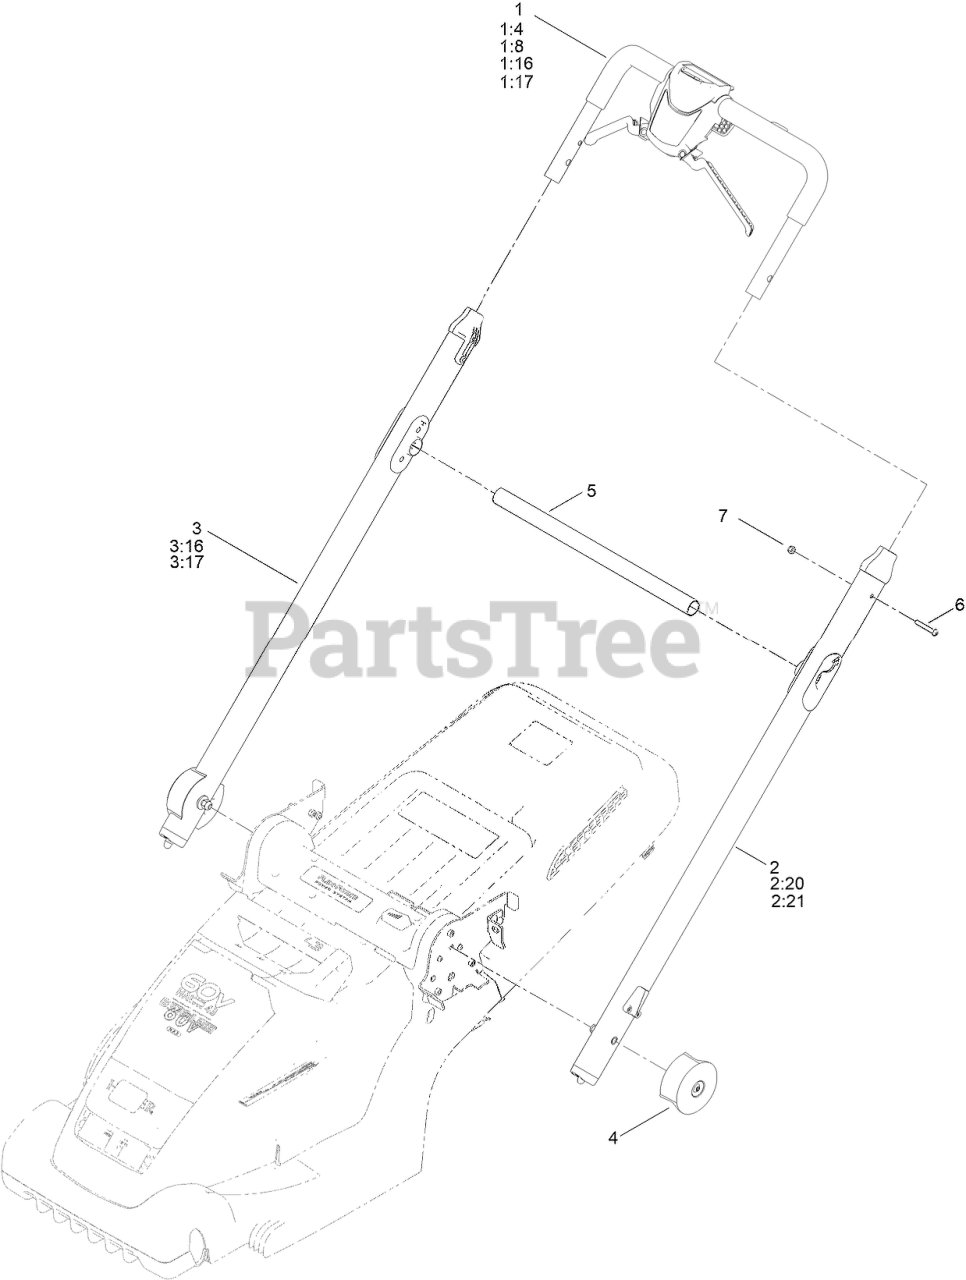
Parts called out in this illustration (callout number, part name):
1	CONTROL LEVER ASM, PROPELLED
1:4	TOP BUTTON KIT
1:8	UPPER LEVER KIT (43)
1:16	LOWER LEVER KIT
1:17	SPEED CONTROLLER WHEEL KIT
2	HANDLEBAR ASM, LH
2:20	HANDLEBAR BRACE - INNER
2:21	HANDLEBAR BRACE, OUTER
3	HANDLEBAR ASM, RH
3:16	HANDLEBAR BRACE - INNER
3:17	HANDLEBAR BRACE, OUTER
4	HANDLEBAR END CAP
5	BRACE, HANDLEBAR RELEASE
6	BOLT, M6X40
7	NUT, M6, NYLOC
